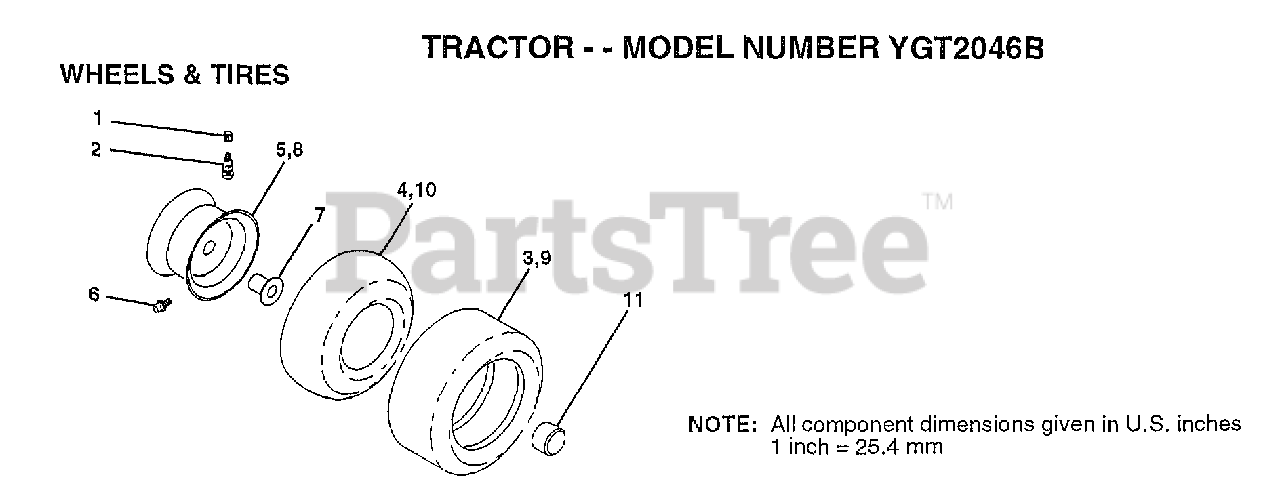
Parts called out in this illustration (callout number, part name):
1	VALVE CAP
2	VALVE STEM LT
4	TUBE.5.3/4.5/6
5	"RIM ASM 8"" FRT"
6	FITTING LT
7	"FLANGE, BEARING"
8	RIM.REAR.
9	TIRE.R.23X9.5-12
10	TUBE.23X8/10-12
11	HUB CAP
